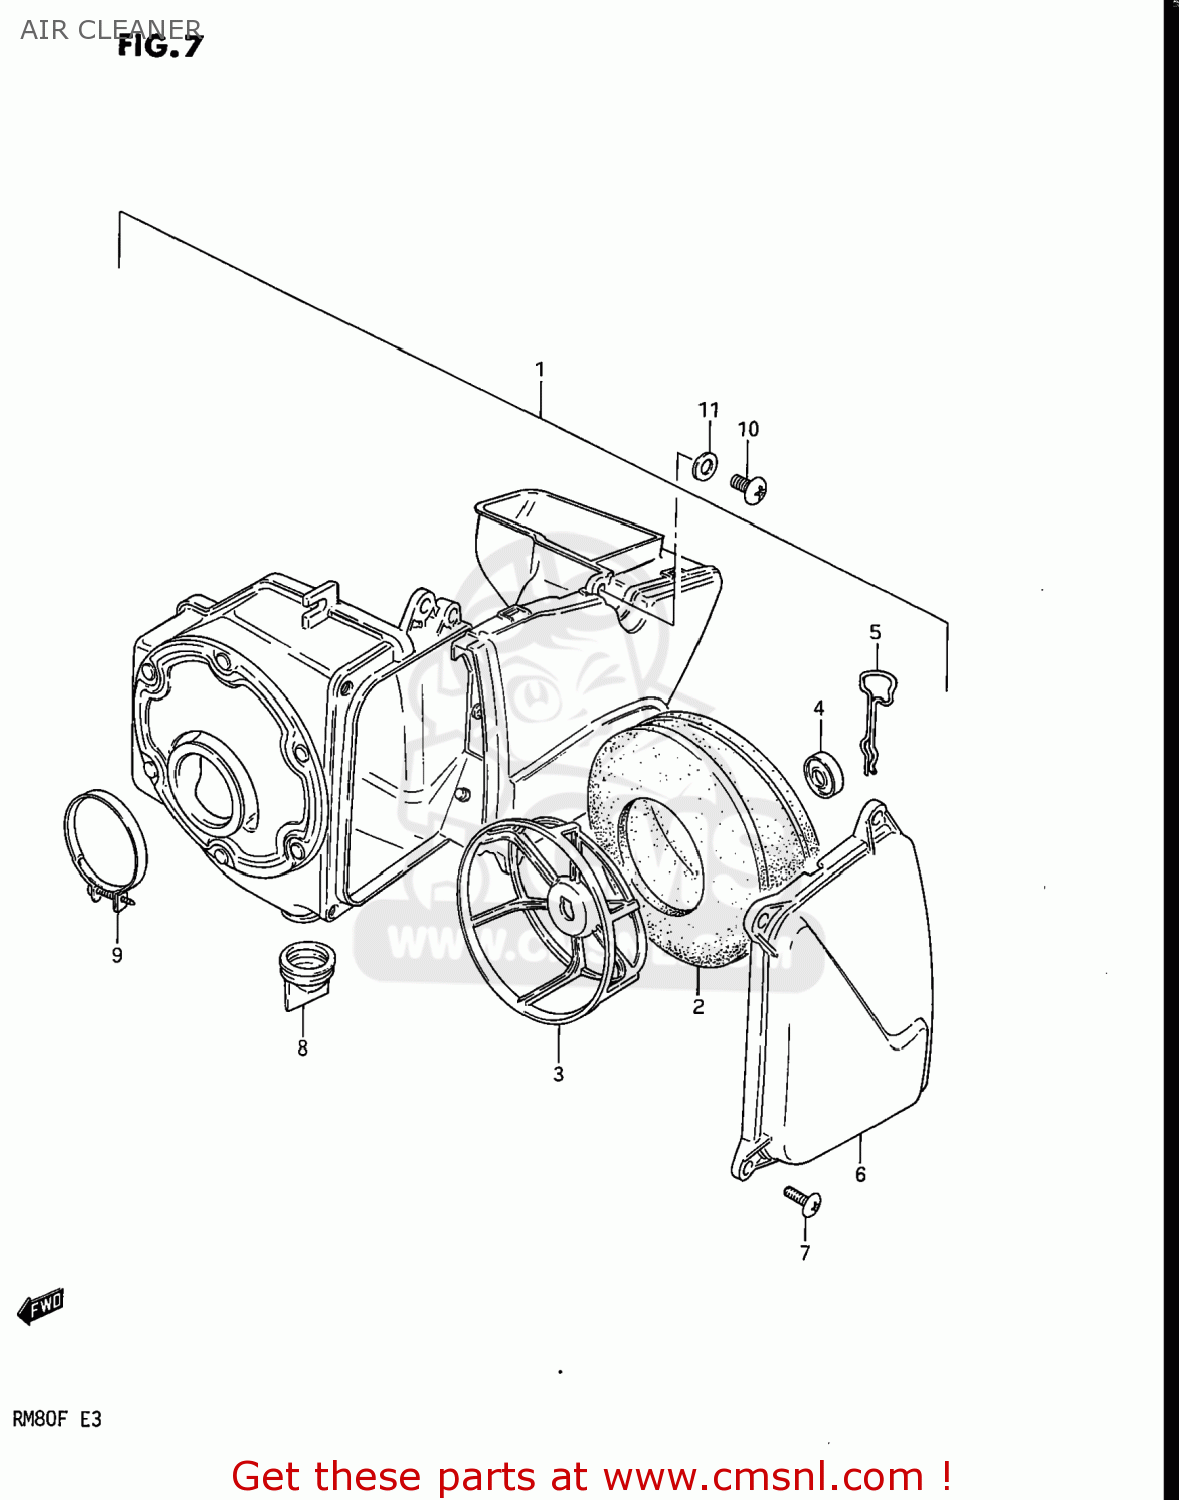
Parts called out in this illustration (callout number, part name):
1	CLEANER ASSEMBLY,AIR
2	FILTER,AIR CLEANER
3	HOLDER,AIR CLEANER
4	WASHER
5	PIN,SNAP
6	CAP,AIR CLEANER
7	SCREW M5X12 DIN 7985/N
8	HOSE,AIR CLEANER DRAIN
9	CLAMP
10	SCREW
11	WASHER
